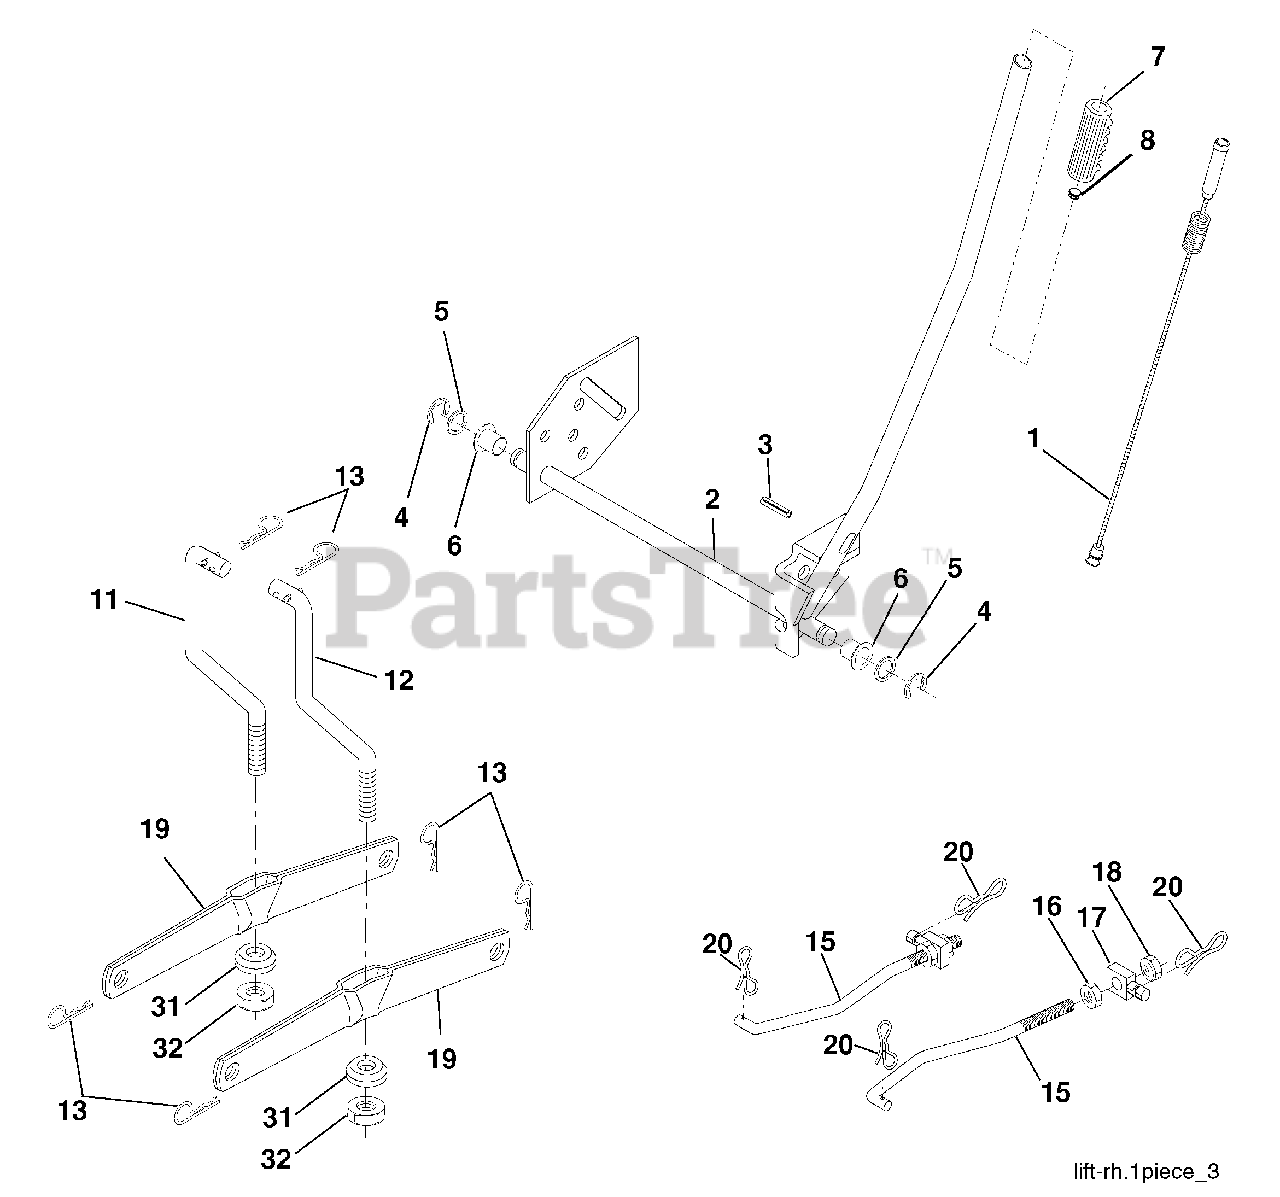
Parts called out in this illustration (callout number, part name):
1	Wire Asm Inner/Sprg w/plunger
2	Shaft Asm Lift RH
3	Pin Groove 1 500 Zinc
4	E Ring #5133-62
5	Washer 21/32 x 1 x 21 Ga.
6	Bearing Nylon Blk 629 Id
7	Grip Handle
8	Button Plunger Black
11	Link Lift LH Fixed Length
12	Link Lift RH Fixed Length
13	Retainer Spring
15	Link Front
16	Nut Jam Hex 1/2-13 unc
17	Trunnion
18	Nut Lockw/Wsh 1/2-13 unc
19	Arm Suspension Rear
20	Pin Cotter 7/16 Bow Tie Lock
31	Bearing Pvt Lift
32	Nut Crownlock 3/8-24
